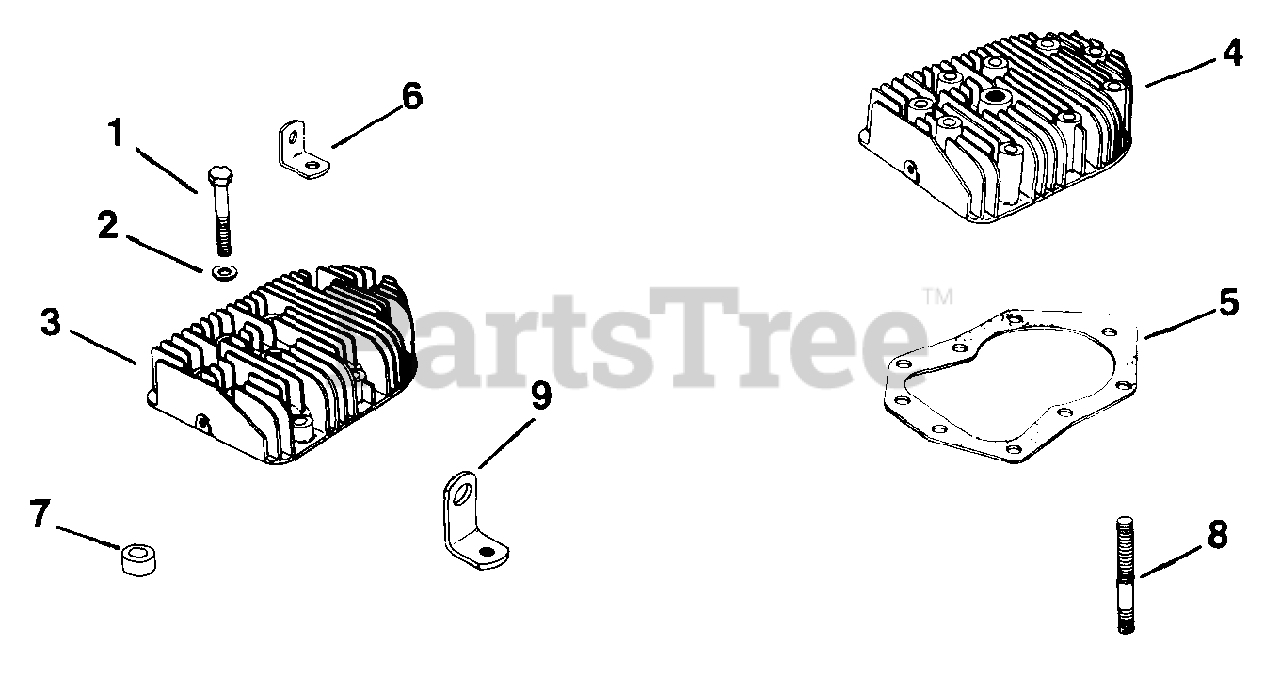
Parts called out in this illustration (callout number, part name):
1	SCREW
2	WASHER, FLAT 13/32"
3	HEAD
5	GASKET, HEAD
6	STRAP, LIFTING
